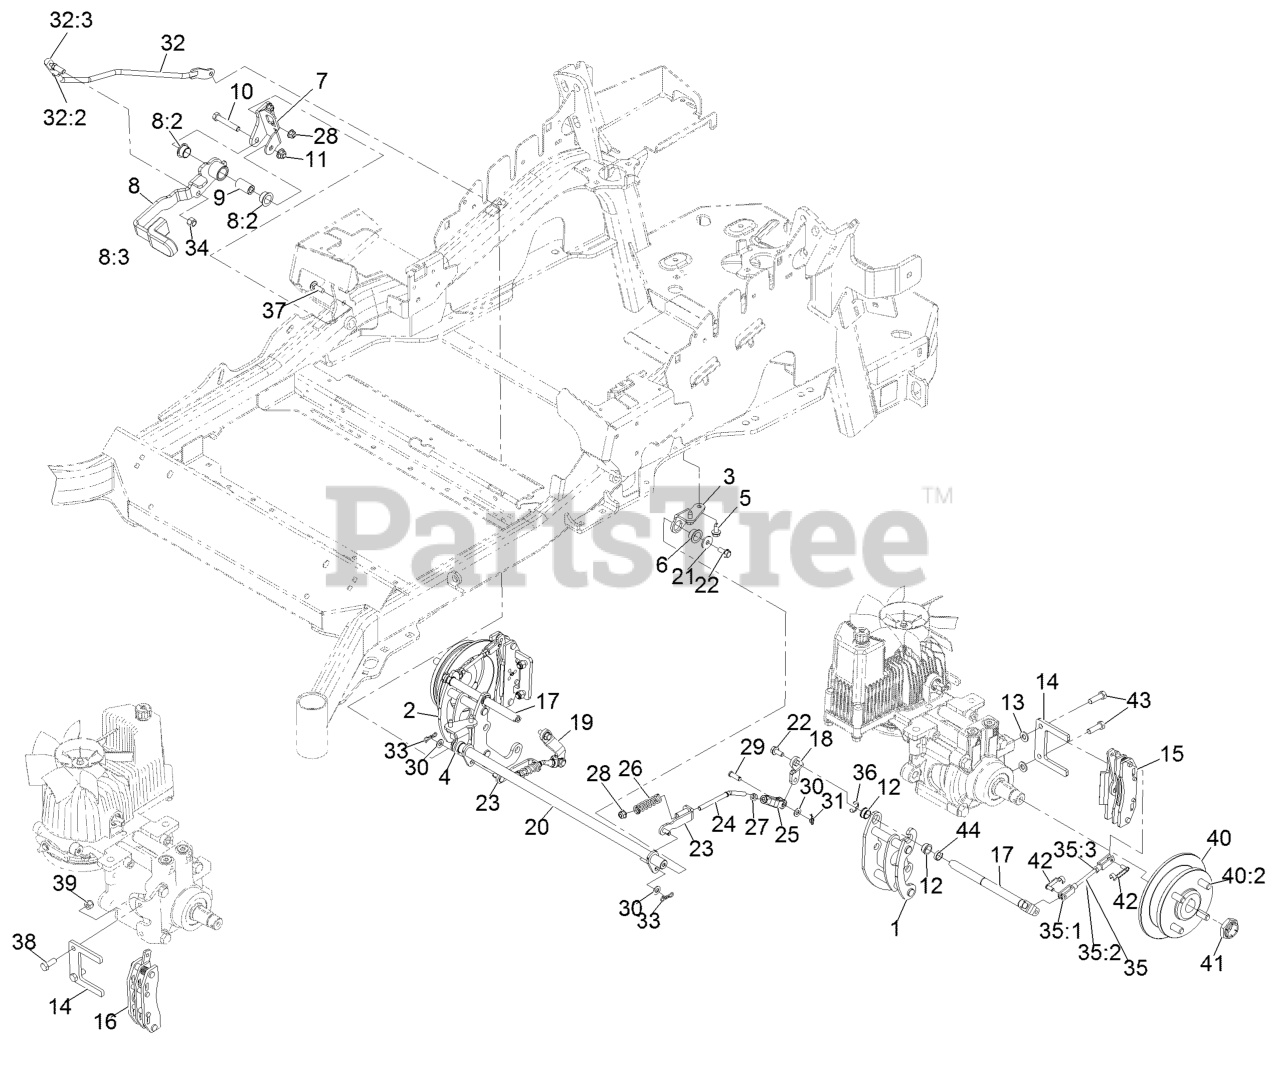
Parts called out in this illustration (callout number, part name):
1	Mount-Bellcrank, LH
2	Mount-Bellcrank, RH
3	Mount-Pivot, LH
4	Mount-Pivot, RH
5	Screw-HWH 5/16-18 X 3/4 Tf
6	Bushing-Flanged
7	Bracket-Mount
8	Brake Lever ASM W/ Grip
8:2	Bushing-Flanged
8:3	Grip-Lever
9	Handle-Pivot, Brake
10	Screw-HH 3/8-16 X 2 1/4
11	Nut-Nyloc 3/8-16 Flg
12	Bushing-Igus
13	Washer-3/8 SAE
14	Plate-Mount, Brake
15	Caliper-Brake
16	Caliper-Brake, RH
17	Bellcrank
18	Arm-Inner, LH
19	Arm-Inner, RH
20	Shaft-Cross
21	Washer-Flat
23	Bracket-L
24	Linkage-Mid
25	Yoke-Offset
26	Spring-Compression
27	Nut-Jam 5/16-24
28	Nut-Nyloc 5/16-18 Flg
29	Pin-Clevis 5/16 X 1 49/64
30	Washer-5/16 SAE
31	Pin-Cotter, Locking
32	Front Linkage ASM
32:2	End-Tie Rod, RH
32:3	Nut-Jam 3/8-24
33	Pin-Cotter, Locking
34	Nut-Nyloc 3/8-24
35	Rear Linkage ASM
35:1	Yoke
35:2	Linkage, Rear
35:3	Nut-Jam 1/4-28
37	Bolt-Carriage 5/16-18 X 1
38	Screw-HH 3/8-16 X 1
39	Nut-Nyloc 3/8-16
40	Wheel Hub ASM
40:2	Stud-Wheel
41	Locknut
42	Pin-Clevis, Spring
43	Screw-HH 3/8-16 X 1 1/4 Patch Lock
